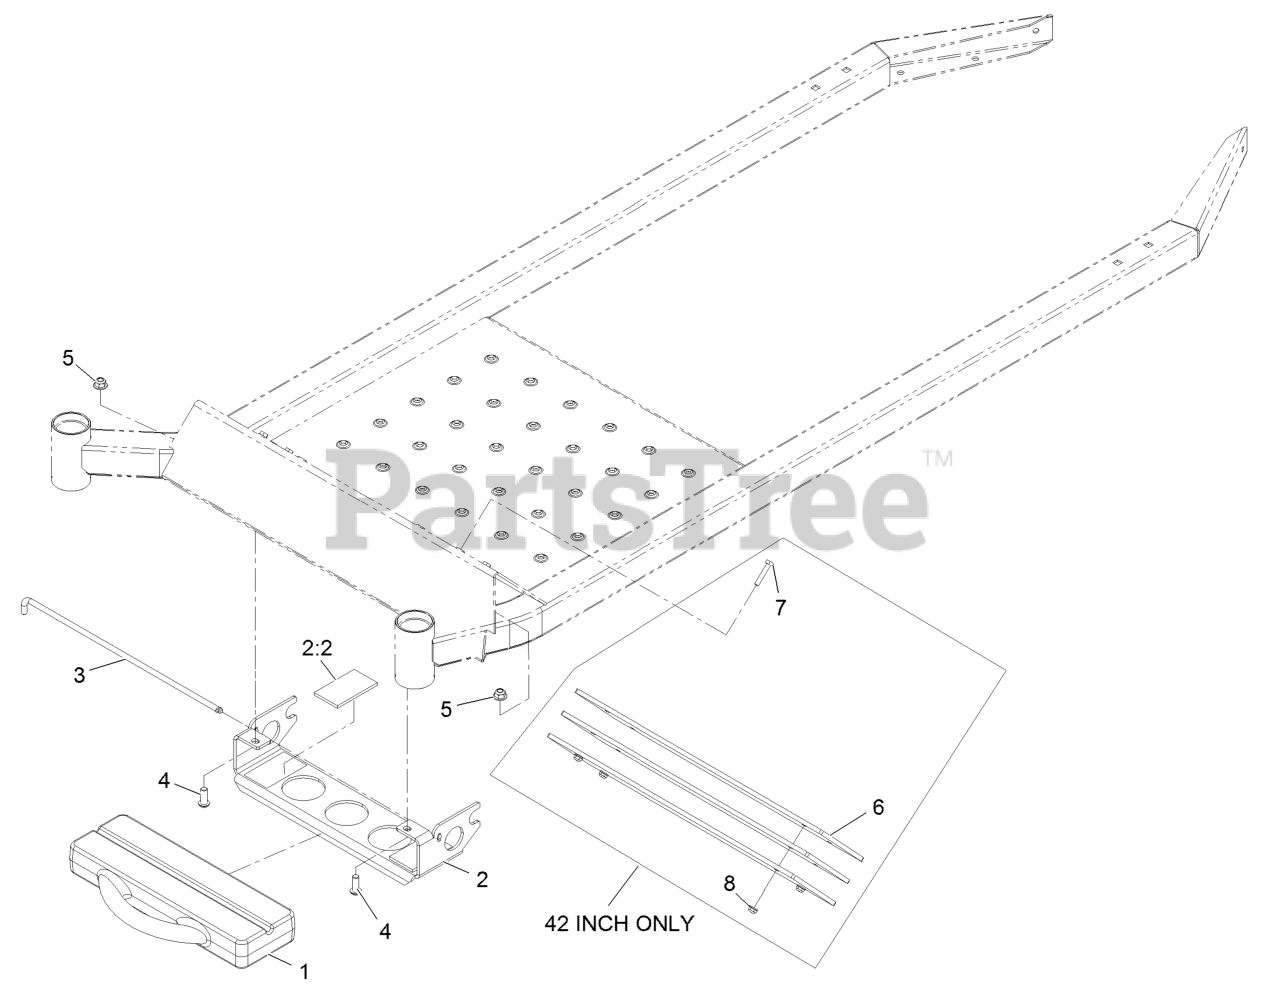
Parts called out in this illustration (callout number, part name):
2	BRACKET ASM
2:2	CUSHION-RUBBER
3	PIN-WEIGHT
4	SCREW-HSBH
5	NUT-HF, NI
6	WEIGHT,BAGGER
7	SCREW-HH
